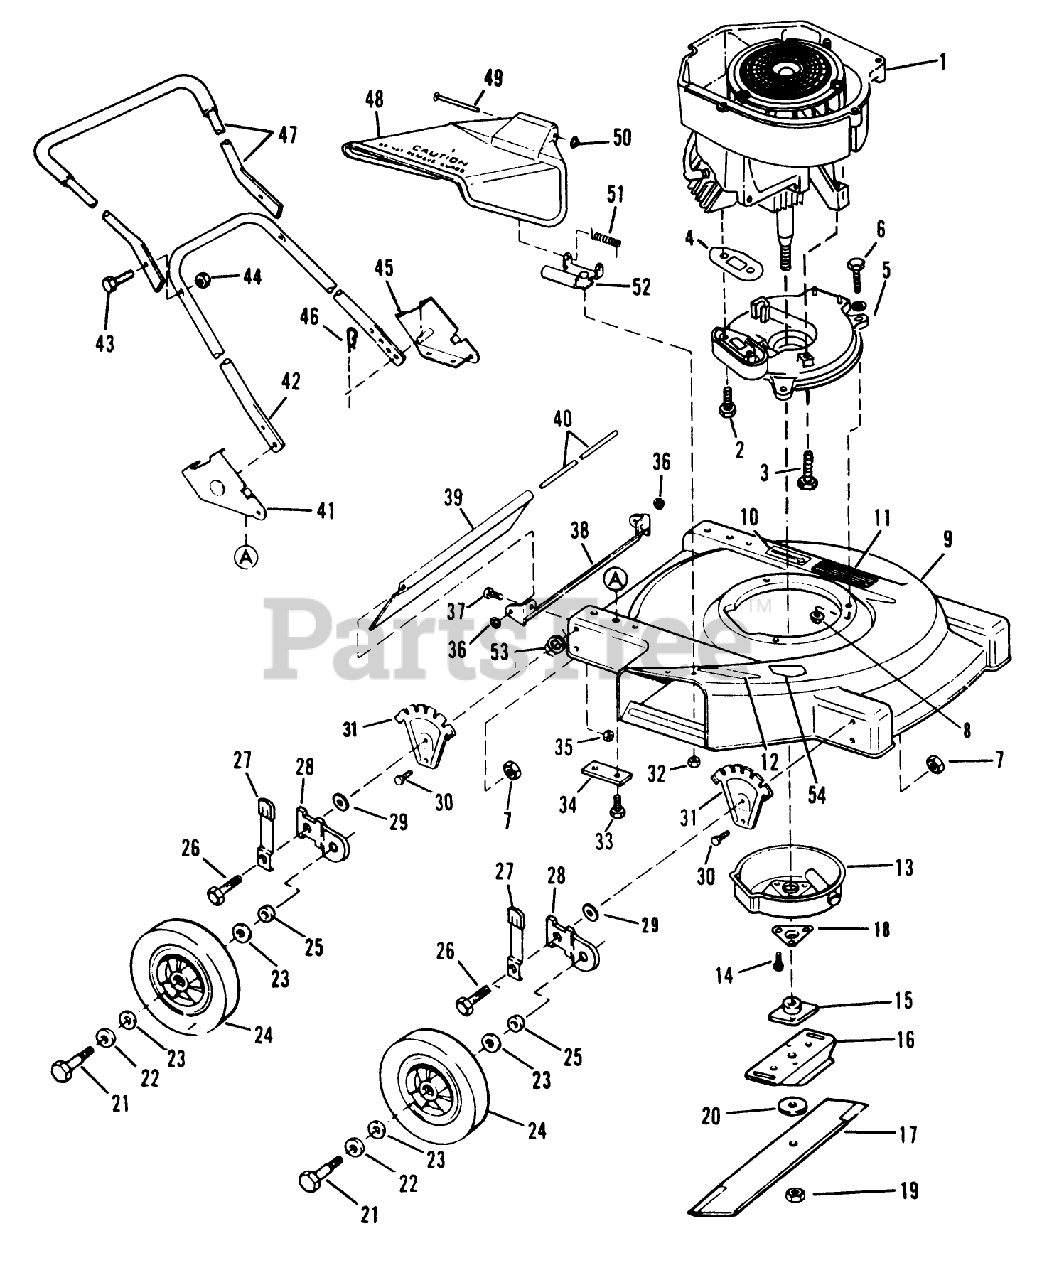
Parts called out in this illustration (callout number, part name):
2	SCREW V
5	PLATE,MUFFLER F
6	SCREW
7	LOCKNUT
8	NUT-LOCK F
11	PAD FOOT
14	SCREW
15	PLATE AND COLLAR ASM
17	BLADE EURO WHIRL
18	SUPPORT F
19	NUT-BLADE
20	WASHER
21	BOLT WHEEL
22	SPACER
23	WASHER
25	WASHER WROUGHT
26	BOLT
27	KNOB&SPRING FORMCO
29	WASHER
32	LOCKNUT E
33	SCREW
35	LOCKNUT E
38	BRACKET (12)
39	TRAILING SHIELD
43	SCREW - USE 137-3042
44	LOCKNUT E
46	HAIR PIN
48	CHUTE DEFLECTOR AY
49	PIN
52	HINGE & SCREW ATA
53	WASHER
